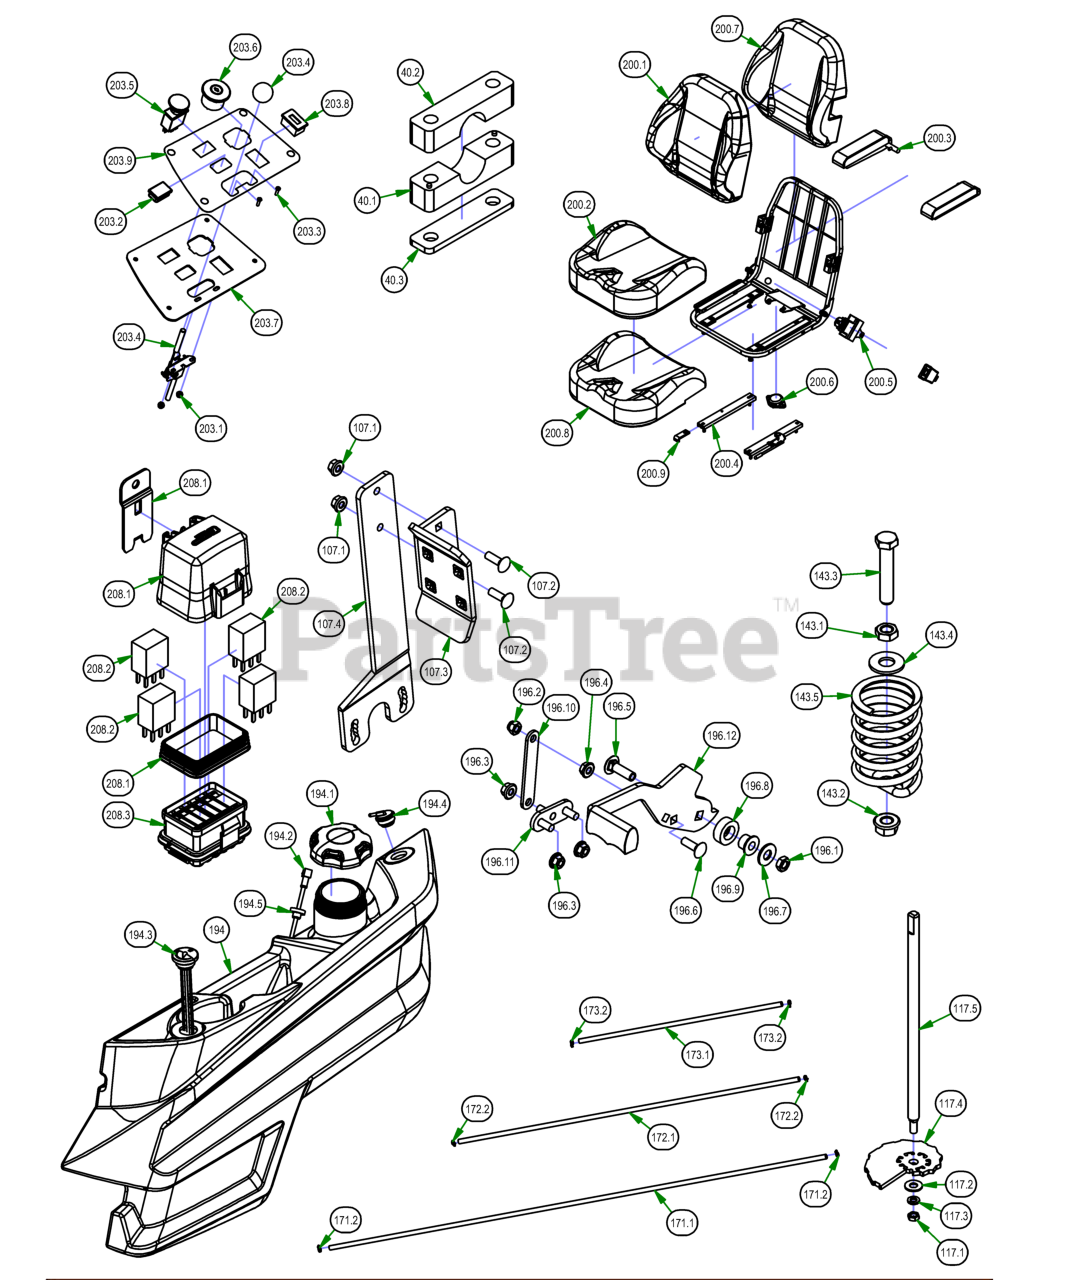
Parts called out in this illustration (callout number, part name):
40	Pillow Block Kit
40.1	Pillow Block MZ male
40.2	Pillow Block MZ female
40.3	Pillow Block Strap
107	Foot Pedal Assembly
107.1	5/16-18 NYLON INSERT FLANGE LOCKNUT ZINC
107.2	5/16-18 X 1 CARRIAGE BOLT (GR.8) ZINC
107.3	2017 MZ/ZT Shallow Foot Pedal
107.4	2017 MZ/ZT Deck Pedal Lever
117	ZT Deck Height Bar Assembly
117.1	3/8-24 HEX NUT ZINC YELLOW
117.2	3/8 FLAT WASHER USS (1" OD) ZINC
117.3	3/8 SPLIT LOCKWASHER ZINC
117.4	2017 MZ/ZT Cam Plate
117.5	2017 Deck Height Dial Rod ZT
143	Seat Spring Assembly
143.1	3/8-16 Half Jam Nut
143.2	3/8-16 HEX SERRATED FLANGE NUT HARD/ZINC
143.3	3/8-16 X 2 HEX CAP SCREW (GR.5) ZINC
143.4	3/8 FLAT WASHER USS (1" OD) ZINC
143.5	Seat Spring
171	Honda Maverick Fuel Line Assembly
171.1	1/4 Fuel Line, 54"
171.2	1/4 Fuel Hose Clamp
172	37" Fuel Line Assembly
172.1	37" 1/4 Fuel Line
172.2	1/4 Fuel Hose Clamp
173	2015 ZT KawaFuel Line Assy-22"
173.1	1/4 Fuel Line
173.2	1/4 Fuel Hose Clamp
194	2021 Maverick Left Side Tank
194.3	Fuel Gauge w/Grommet
194.4	Rollover Valve W/Grommet
194.5	Pick-Up Grommet
196	2021 Load Balanced Brake Handle Assembly
196.1	3/8-16 HEX JAM 2-WAY REVERSIBLE CENTER LOCKNUT ZINC
196.2	5/16-18 NYLON INSERT CAP LOCKNUT ZINC (BLK CAP)
196.3	5/16-18 NYLON INSERT FLANGE LOCKNUT ZINC
196.4	5/16-18 HEX SERRATED FLANGE NUT HARD/ZINC
196.5	3/8-16 X 1-1/4 CARRIAGE BOLT ZINC
196.6	5/16-18 X 1 CARRIAGE BOLT (GR.8) ZINC
196.7	3/8 FLAT WASHER USS (1" OD) ZINC
196.8	2015 Brake Lever Spacer
196.9	.377 ID X .625 OD X .500 HGT X .880 FLNG DIA X .060 FLNG THK
196.10	Brake Cable Extension Plate
196.11	Brake Load Balancer Lower Weldment
196.12	Load Balanced Brake Handle with Grip
200	2021 Maverick Seat
200.1	Back Cover for 071-2102-00
200.2	Seat Cover for 071-2101-00/071-2102-00
200.3	2017 ZT/Maverick/2020 ZTElite/Avenger Arm Rest Kit
200.4	Seat Rails for Outlaw Seat/2020 ZT Elite/ZTAvenger
200.5	Seat Belt for 071-5080-17
200.6	13/14 MZ/Outlaw Seat Switch
200.7	Foam Molded Back for 071-2102-00
200.8	Seat Cover Molded Foam for 071-2040-18/071-5080-18
200.9	Black Seat stop from Seat King
203	2019 ZT/Maverick Control Panel Assembly
203.1	10-24 Nylon Insert Locknut Zinc Orange Nylon
203.2	Light Plug
203.3	10-24 X 5/8 BS Button Head Bolt
203.4	Throttle Lever Assembly
203.5	PTO Engager
203.6	Ignition Switch
203.7	Control Panel
203.8	Tachometer
203.9	2018 MZ/Magnum/ZT/Maverick Control Panel Decal
208	Wiring Harness
208.1	Relay Block Cover Replacement Kit
208.3	Wiring Harness
